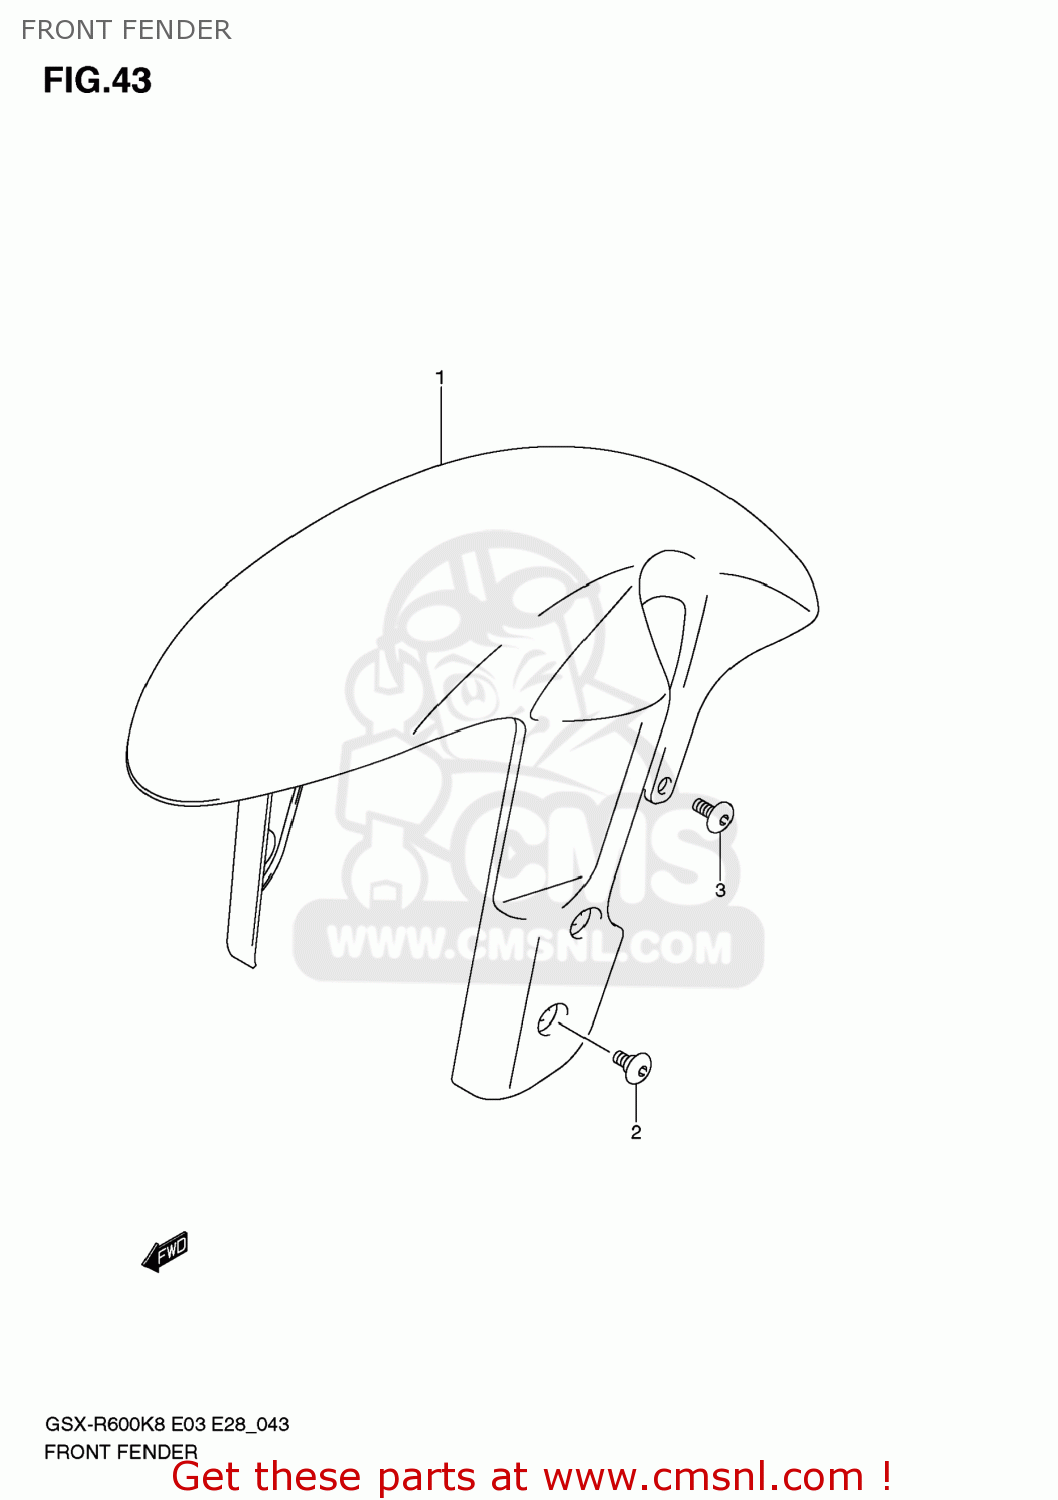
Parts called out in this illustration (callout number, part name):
1	FENDER ASSY,FR(BLUE)
2	SCREW(6X12)
3	SCREW(6X16)
